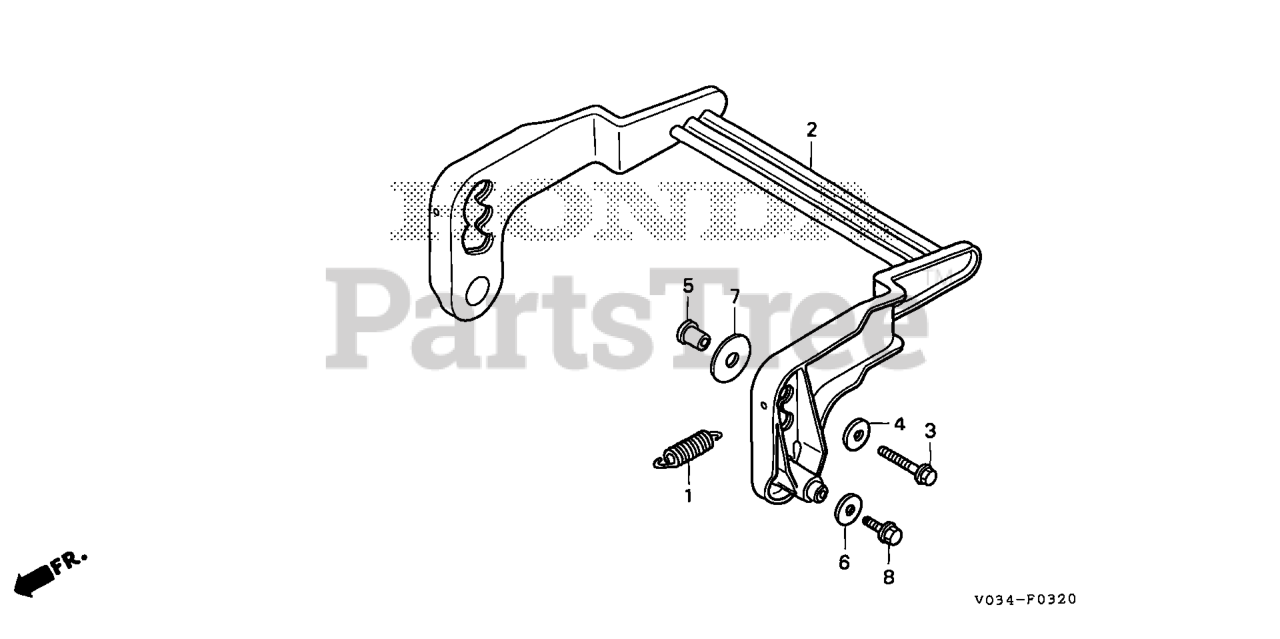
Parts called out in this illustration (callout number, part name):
1	SPRING, HEIGHT ADJUSTING
2	PLATE, HEIGHT ADJUSTING
3	BOLT, FLANGE (8X30)
4	WASHER, PLAIN (8X23X3.2)
5	COLLAR, HEIGHT ADJUSTING
6	WASHER, PLAIN (8MM)
7	WASHER, PLAIN (12MM)
8	BOLT, FLANGE (8X14)
